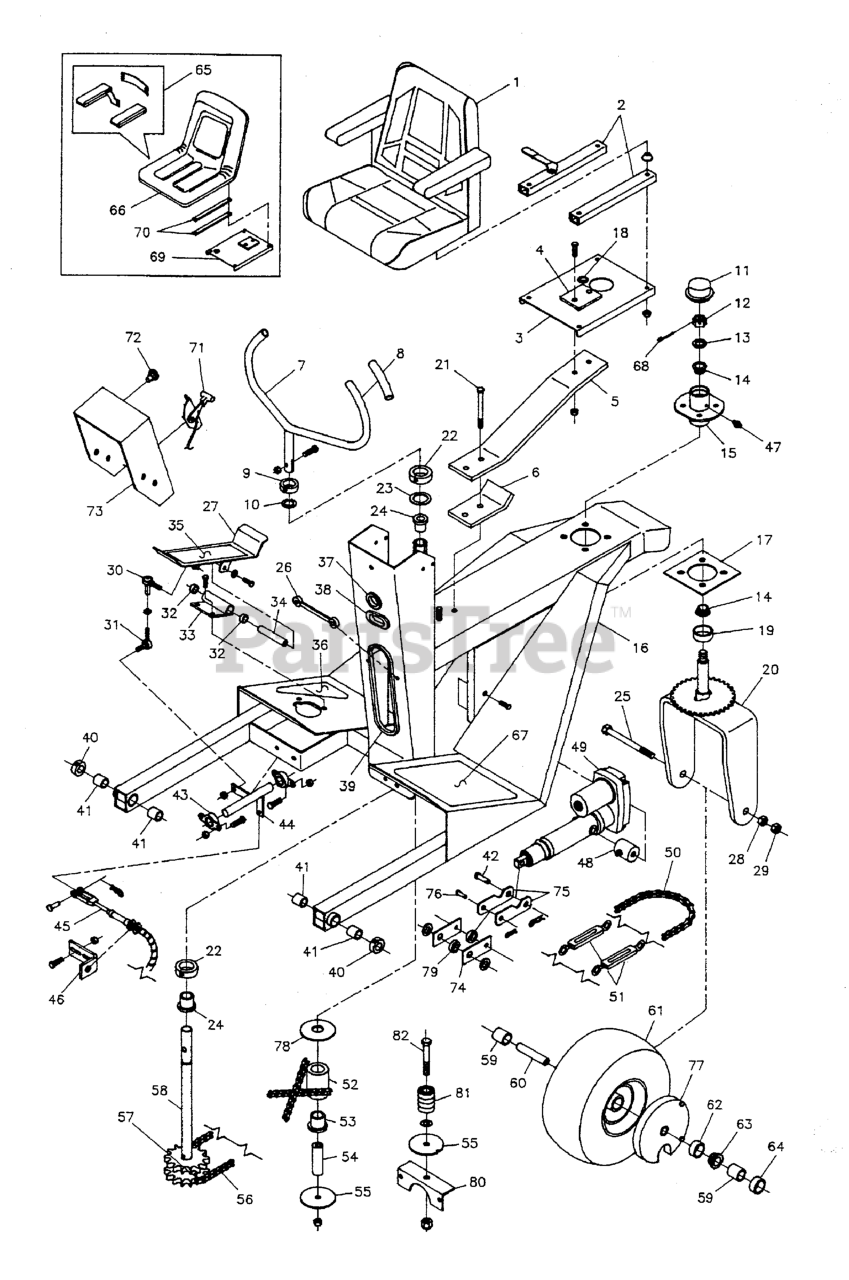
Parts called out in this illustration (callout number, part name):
1	SEAT, Black & Silver, Complete
1	CUSHION, BACK
1	CUSHION, BOTTOM
1	ARM REST, RH
1	ARM REST, LH
2	SEAT ADJUSTER RAILS (set of 2)
3	PLATE, Seat
4	SUPPORT, Seat Plate
5	SEAT SPRING
6	SUPPORT, Seat Spring
7	STEERING HANDLE
8	GRIP, Foam
9	COLLAR, 1" Split
10	Snap Ring
11	CAP
12	NUT, 3/4-16 Hex Slotted
13	WASHER, 3/4 SAE
14	BEARING, Tapered Roller
15	HUB, Steering
16	TRAILER WELDMENT
17	Steering Hub Support
18	GROMMET, 1/2"
19	SEAL, GREASE
20	MOUNT, Steering Tire
21	BOLT, 7/16-20 X 5
22	COLLAR, 1-1/4" Split
23	SHIM
24	BUSHING, Flange
25	BOLT, 5/8-11 x 9-1/2
26	RUBBER STRAP
27	FOOT CONTROL PEDAL
28	NUT, 5/8-11 Hex
29	NUT, 5/8-11 Hex Side Lock
30	BALL JOINT, 3/8" Female Studded
31	BALL JOINT, 3/8-24 Male, Studded
32	BUSHING, Brass
33	FOOT PEDAL PIVOT MOUNT, Complete
34	SHAFT, Pedal Pivot
35	SAFETY WALK
36	SAFETY WALK
37	GROMMET, 7/8"
38	GROMMET, 1-1/4"
39	Body Molding, 24" Long
40	COLLAR, 3/4" Split
41	BUSHING, Plastic
42	PIN, Clevis
43	CABLE, Speed Control
44	BELL CRANK
45	CABLE, Speed Control
46	CABLE BRACKET
47	GREASE FITTING
48	ACTUATOR MOUNT
49	ELECTRIC ACTUATOR
50	CHAIN, #40 Roller, 36 Links
51	TURNBUCKLE
52	Steering Roller Assembly
53	Bushing
54	Steering Tube
55	WASHER, Chain
56	CHAIN, #40 Roller, 31 Links
57	CONNECTOR, #40 Chain Link
58	SHAFT, Steering Sprocket
59	SPACER, 1.01 X 1.25 X 2.06
60	STEERING TIRE AXLE
61	WHEEL & TIRE ASSEMBLY, 18 x 7.5 x 8, White, Complete
62	BEARING CUP
63	BEARING, Tapered Roller
65	Arm Rest Kit
65	Arm Rest Right/Left (interchangeable)
67	SAFETY WALK
68	PIN, COTTER, 1/8 X 1-1/4
69	Seat Plate
70	Seat Plate Spacer
71	CABLE, Throttle, 54"
72	CABLE, CHOKE CONTROL, 45
72	CABLE, Choke Control, 57"
74	ACTUATOR LINK, Upper
74	Linkage Rod
75	ACTUATOR LINK, Lower
76	CLEVIS PIN, 3/8 x 1
77	WHEEL WEIGHT
78	Chain Washer Top
79	SPACER, .63 x 1.06 x .23
80	MOUNT, Chain Roller
81	BEARING, Roller
82	BOLT, 5/8-11 x 3" GD5 CZ
